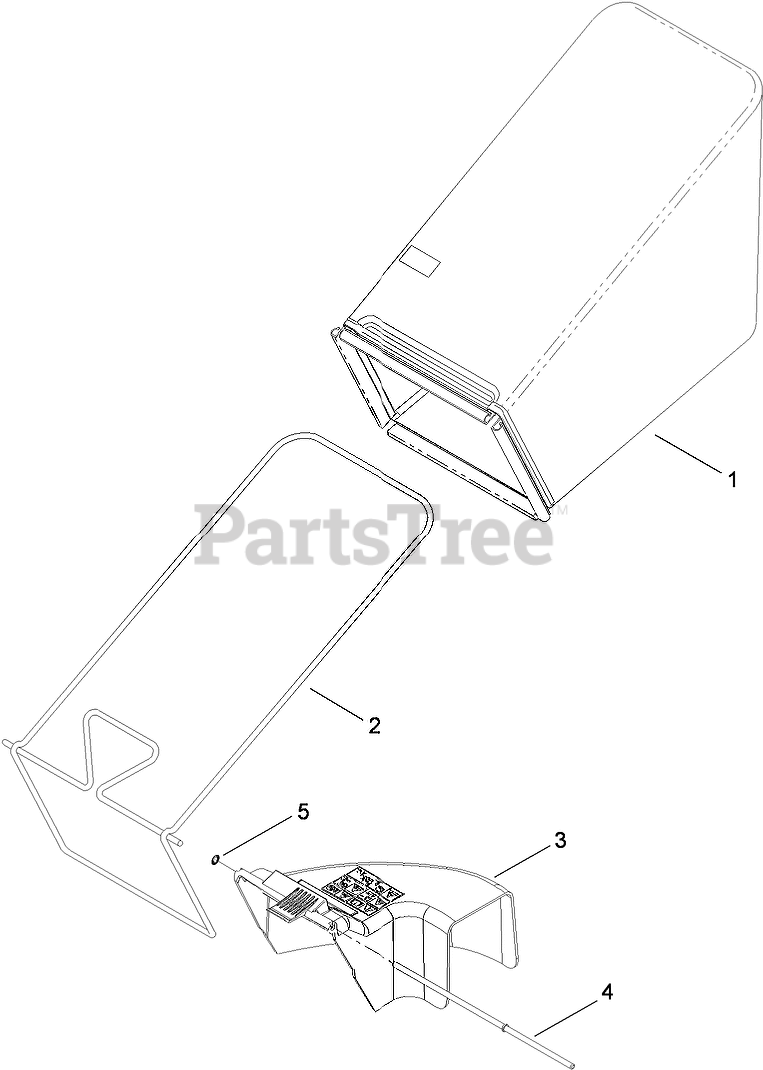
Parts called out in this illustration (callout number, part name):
1	GRASS BAG ASM
2	FRAME-BAG
3	REAR DEFLECTOR ASM
5	RING-RETAINING
